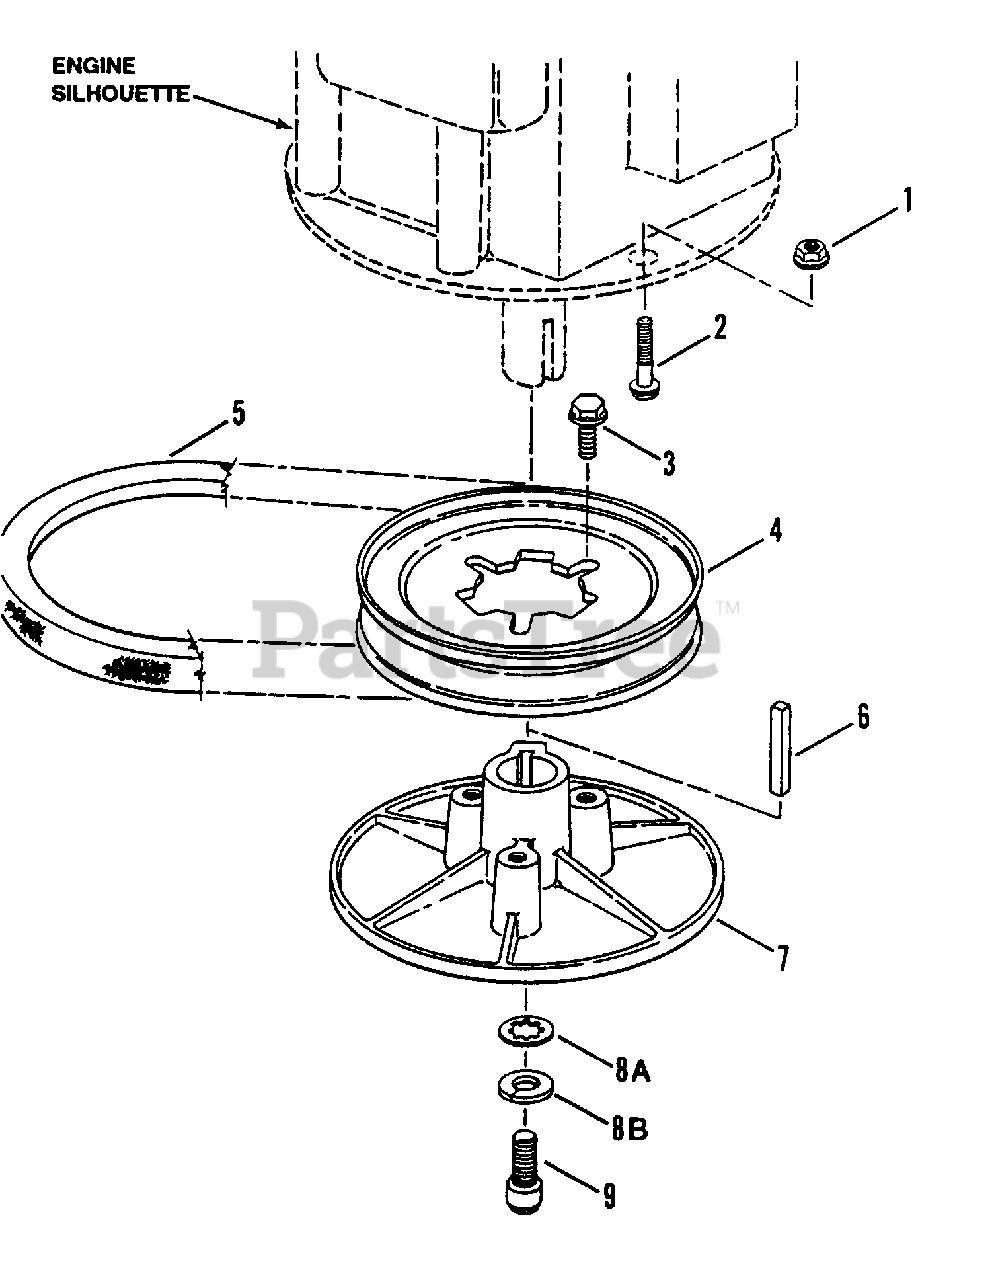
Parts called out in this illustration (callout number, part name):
1	NUT, 5/16-18 Hex Flange Lock
2	BOLT, 5/16-18 x 1 1/2" Hex Flange Lock, Engine Mounting
3	SCREW, 1/4-20 x 5/8" Self-Tapping
4	PULLEY, Drive
5	V-BELT (8 HP) 4L x 62.38" EL Kevlar
5	V-BELT (5 HP) 4L x 62.0" EL Kevlar
6	KEY, 1/4 x 2" (RT5 & 8HP)
6	KEY, Hi-Pro #505 (RT5X)
7	PLATE, Drive (RT5 & 8HP)
7	PLATE, Drive (RT5X)
8A	WASHER, 3/8 Internal Tooth Lock (5HP)
8B	WASHER, 7/18 Split Lock (8HP)
9	SCREW, 3/8-24 x 1" Allen-Head Cap (5HP)
9	SCREW, 7/16-20 x 1" Allen-Head Cap (8HP)
